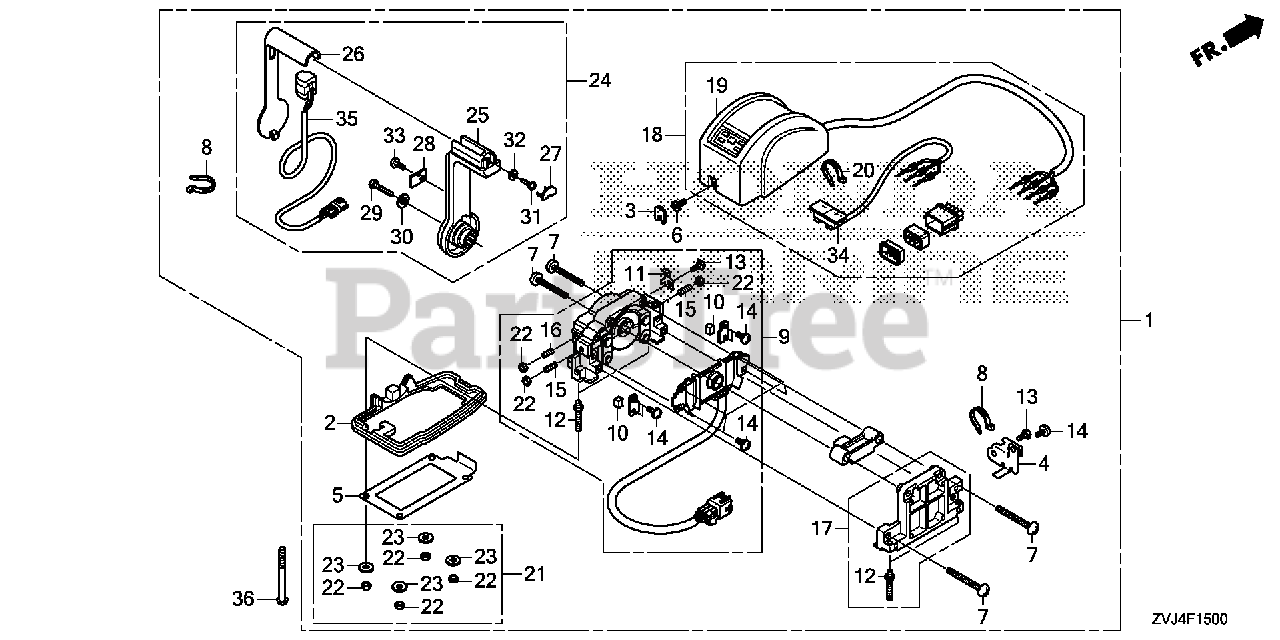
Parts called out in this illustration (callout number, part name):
1	BOX ASSY., REMOTE CONTROL (TOP MOUNT SINGLE)(RH)
2	GASKET (SINGLE)
3	COVER, CAP
4	PLATE, COVER FIX (SINGLE)
5	SHEET, WATERPROOF (SINGLE)
6	BOLT, SOCKET
8	BAND, NYLON
9	HOUSING ASSY., L.
10	SHOE, BRAKE
11	PLATE, HARNESS
12	BOLT, STUD
17	HOUSING ASSY., SINGLE
18	COVER ASSY., SINGLE
19	LED ASSY., COVER (S)
20	BAND, NYLON
21	NUT SET, MOUNTING
24	LEVER ASSY., L.
26	PANEL, LEVER (POWER TRIM-TILT)
27	CAP, LEVER
28	PLATE, LEVER PANEL
34	SWITCH ASSY., SELECT
35	SWITCH ASSY., POWER TRIM-TILT
36	SCREW, PAN (5X65)
